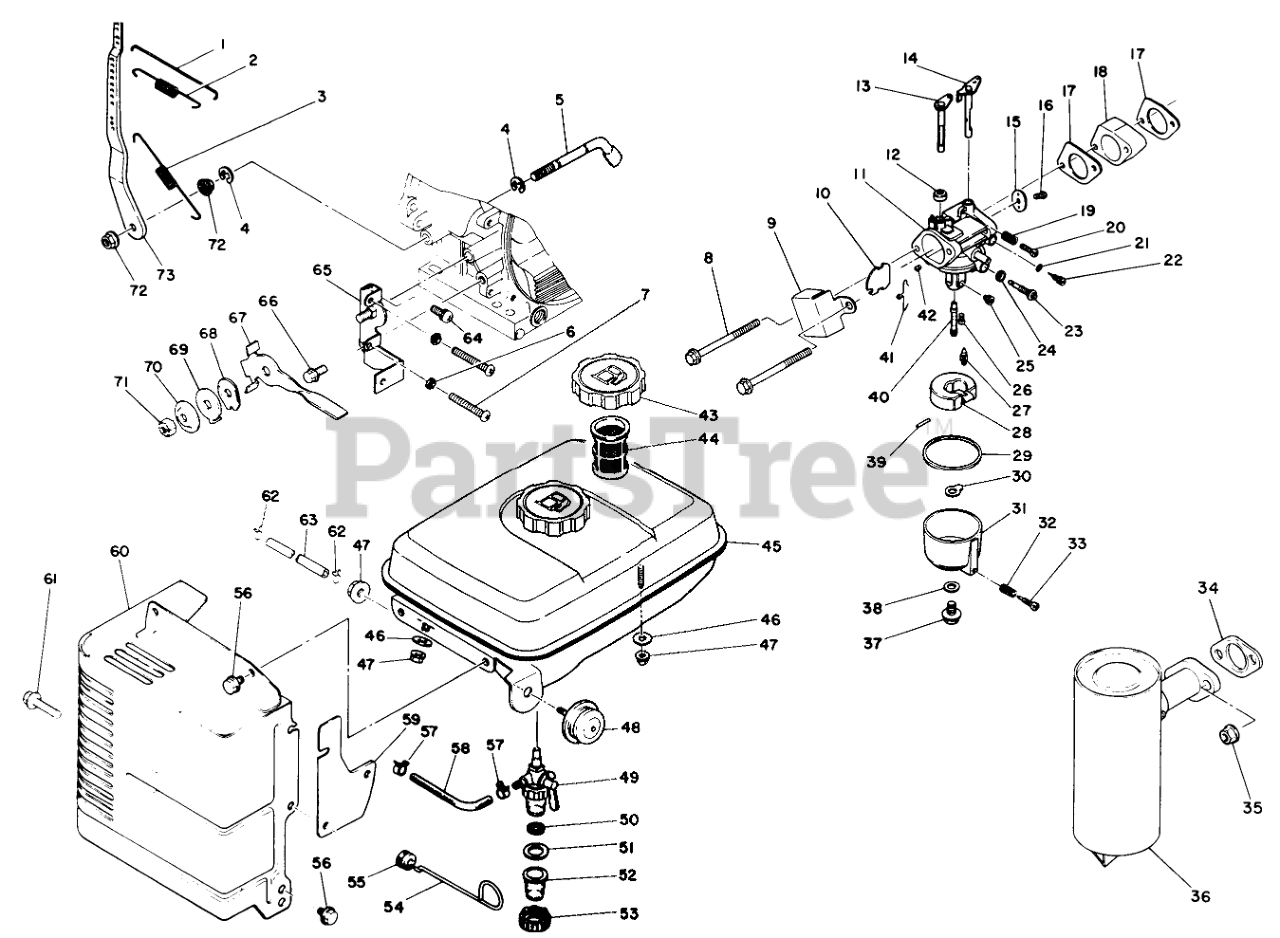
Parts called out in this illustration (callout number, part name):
1	GOV.ROD
2	SPRING-ROD
3	SPRING
4	SNAP RING
5	GOV SHAFT
7	SCREW
9	COVER
10	VALVE
11	Carburetor Assembly (Incl. Ref. #10-16, 19-33 & 37-42)
13	SHAFT
14	THROTTLE SHAFT
15	THROTTLE VALVE
16	SCREW
17	CARB GASKET
18	INSULATOR
19	SPRING
20	SCREW
21	O - RING
22	Valve-Needle (Incl. Ref. #21)
23	SLOW JET
24	GASKET
25	MAIN JET
26	SCREW
27	VALVE
28	FLOAT
29	GASKET
30	GASKET
31	Bowl-Float (Incl. Ref. #32 & 33)
32	SPRING
33	SCREW
34	GASKET
36	MUFFLER
38	GASKET
39	FLOAT PIN
40	MAIN NOZZLE
42	BREATHER
43	FUEL TANK CAP
44	FUEL FILTER
45	Fuel Tank Assembly (Incl. Ref.#43, 44, & 46)
46	GASKET
49	Petcock-Fuel (Incl. Ref. #50-53)
50	SCREEN
51	GASKET
55	GROMMET
59	COVER
60	COVER
62	CLAMP
64	SCREW W/WASHER
65	BRACKET
67	LEVER
68	LEAF SPRING
69	WASHER
70	WASHER
73	GOV.LEVER
